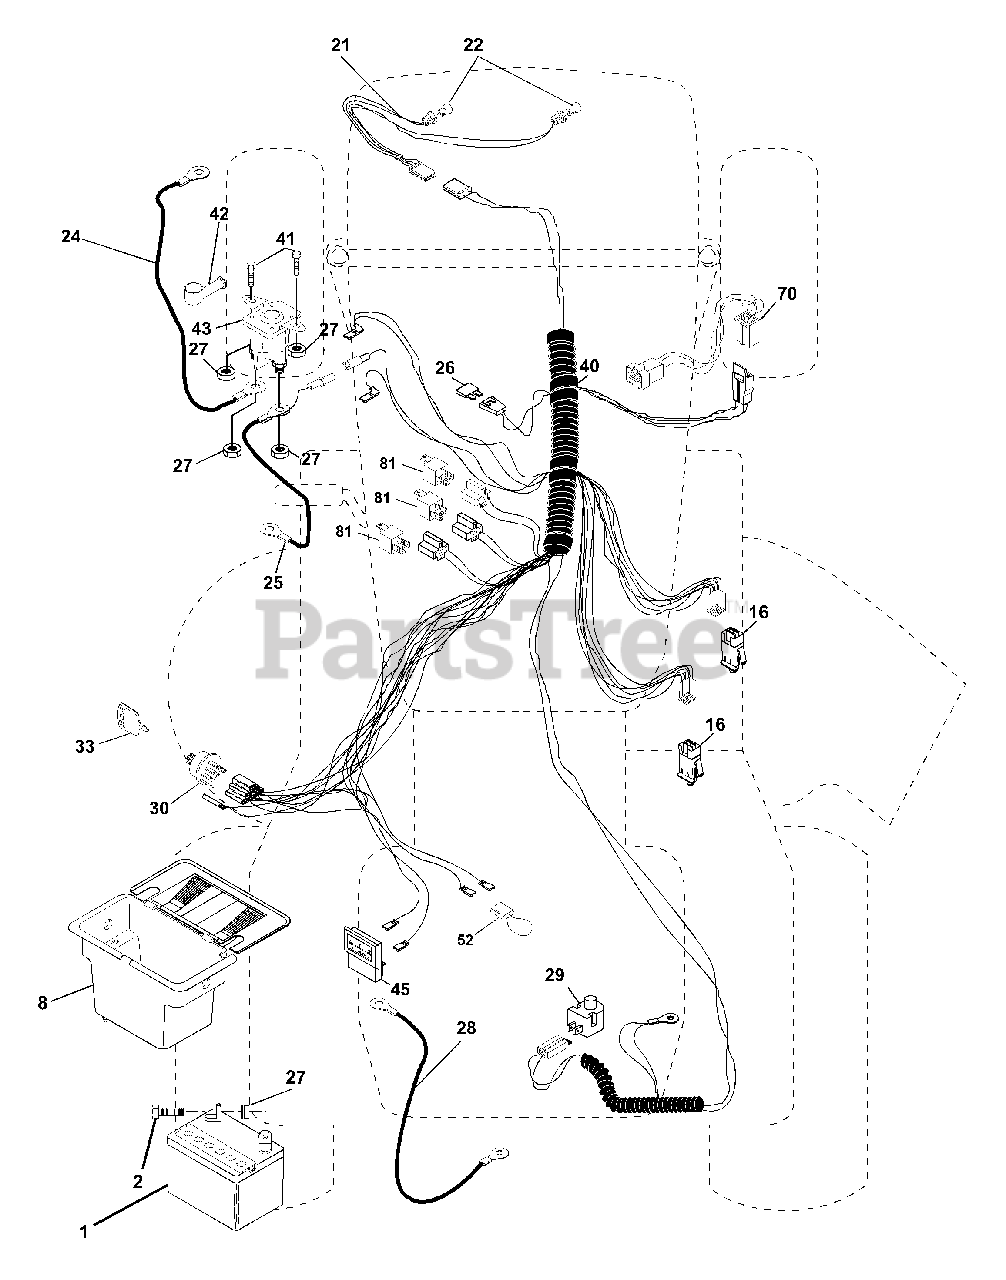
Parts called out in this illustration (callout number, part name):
1	Battery 12 Volt 25 Amp
2	Bolt Hex Hd 1/4-20unc X 3/4
8	Case Battery Mech Hinge
16	Switch Interlock
21	Harness Socket Light
22	Bulb, Light # 1156
24	Cable Battery
25	Cable Battery 6 Ga Red w/16 wire
26	Fuse 15 Amp
27	Nut Keps Hex 1/4-20 Unc
28	Cable Ground 6ga 12 black
29	Switch Plunger
30	Switch Ign
33	Key Ign Molded Generic
40	Harness Ign
41	Bolt Fin Hex 1/4-20uncx 1/2
42	Cover Terminal Red
43	Solenoid
45	Ammeter Rectangular
52	Protection Loop
70	Harness Engine
81	Relay Asm
